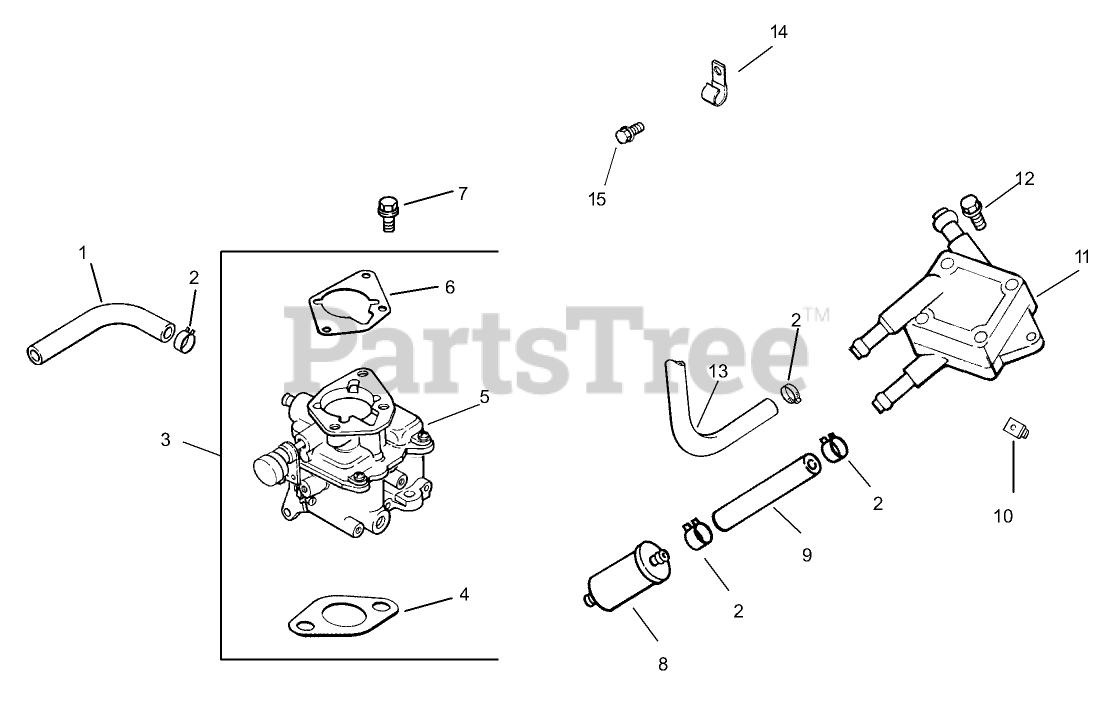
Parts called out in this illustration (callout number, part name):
1	Line-Fuel (9.5)
2	CLAMP-HOSE, SPRING (1/2)
3	Kit, carburetor w/gaskets (Includes 4-6)
4	GASKET-BASE, AIR CLEANER
5	Carburetor assembly (Includes 15-35)
6	Gasket-Carburetor
7	SCREW-FLANGE (M6X1.0X30)
8	Filter-Fuel
9	Line-Fuel (3.5)
10	Nut-Plastic
11	PUMP-FUEL
12	SCREW-TAP (M6X1.7X18)
13	Line-Fuel, Flexible (15.5)
14	CLIP-CABLE
15	Screw-HF (M6x1.0x12)
